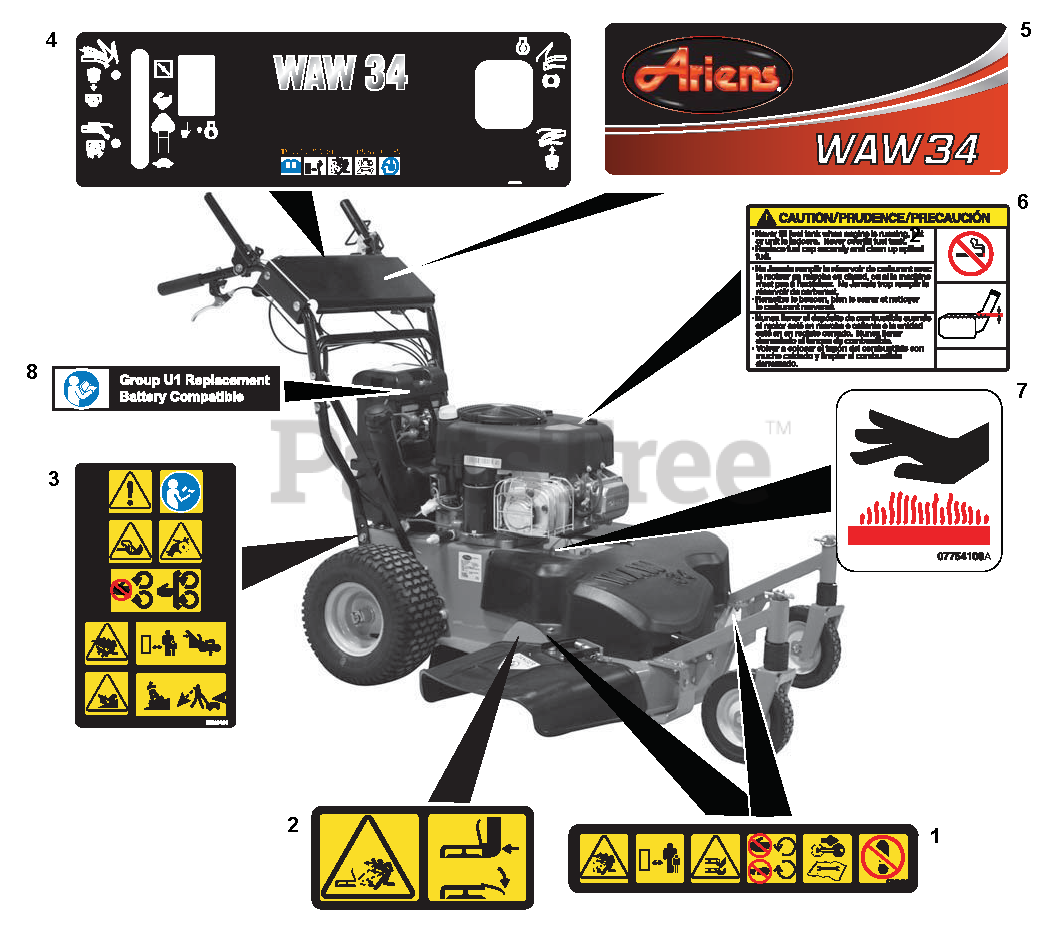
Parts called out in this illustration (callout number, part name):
1	DECAL, DECK SAFETY
2	DECAL, SAFETY - DECK GUARDING
3	DECAL,MAIN SAFETY_WAW LM
4	DECAL, CE WAW OPERATIONAL
5	DECAL,WAW 34 ARIENS DASH
6	DECAL-FUEL, WARNING
7	DECAL, HOT SURFACE
8	DECAL, U1 BATTERY REPLACEMENT
